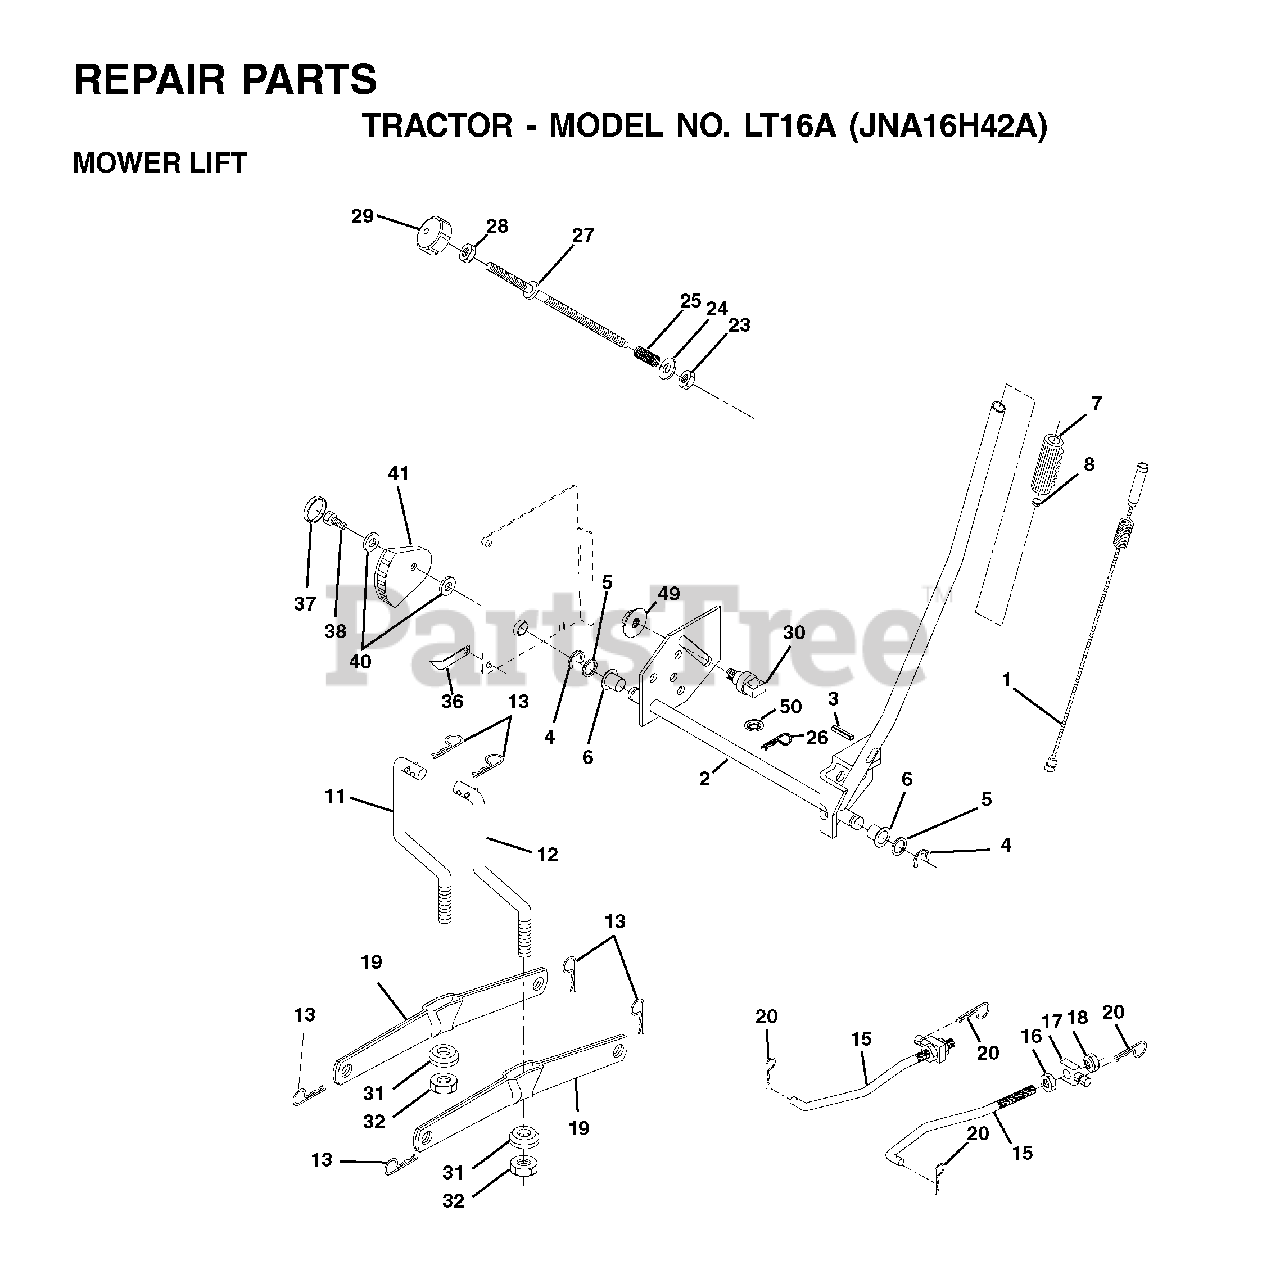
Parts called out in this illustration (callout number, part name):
1	WIRE ASM INNER W/ PLUNGER LT
2	SHAFT ASM R HANDLE
3	PIN GROOVE
4	RETAINING RING LT
6	BEARING.NYLON
7	GRIP HANDLE
8	PLUNGER BUT KIT
11	LINK LIFT LH
12	LINK LIFT RH
13	RETAINER-SPRNG RB
15	LINK.SUSPENSION.FRONT
16	NUT
18	NUT
19	ARM.REAR.SUSPENSION
20	SPRING RETAINER
25	SPRING**
26	RETAINER CLIP
27	ROD ADJ LIFT
28	NUT
29	KNOB INF 3/8-16
31	BEARING.PIVOT.LIFT
32	NUT CROWNLOCK 3/8-24
36	POINTER, HEIGHT INDICATOR
37	PLUG,HOLE
38	SCREW 5/16-18X1
41	IND. HEIGHT STLT
49	NUT
50	NUT PUSH M
